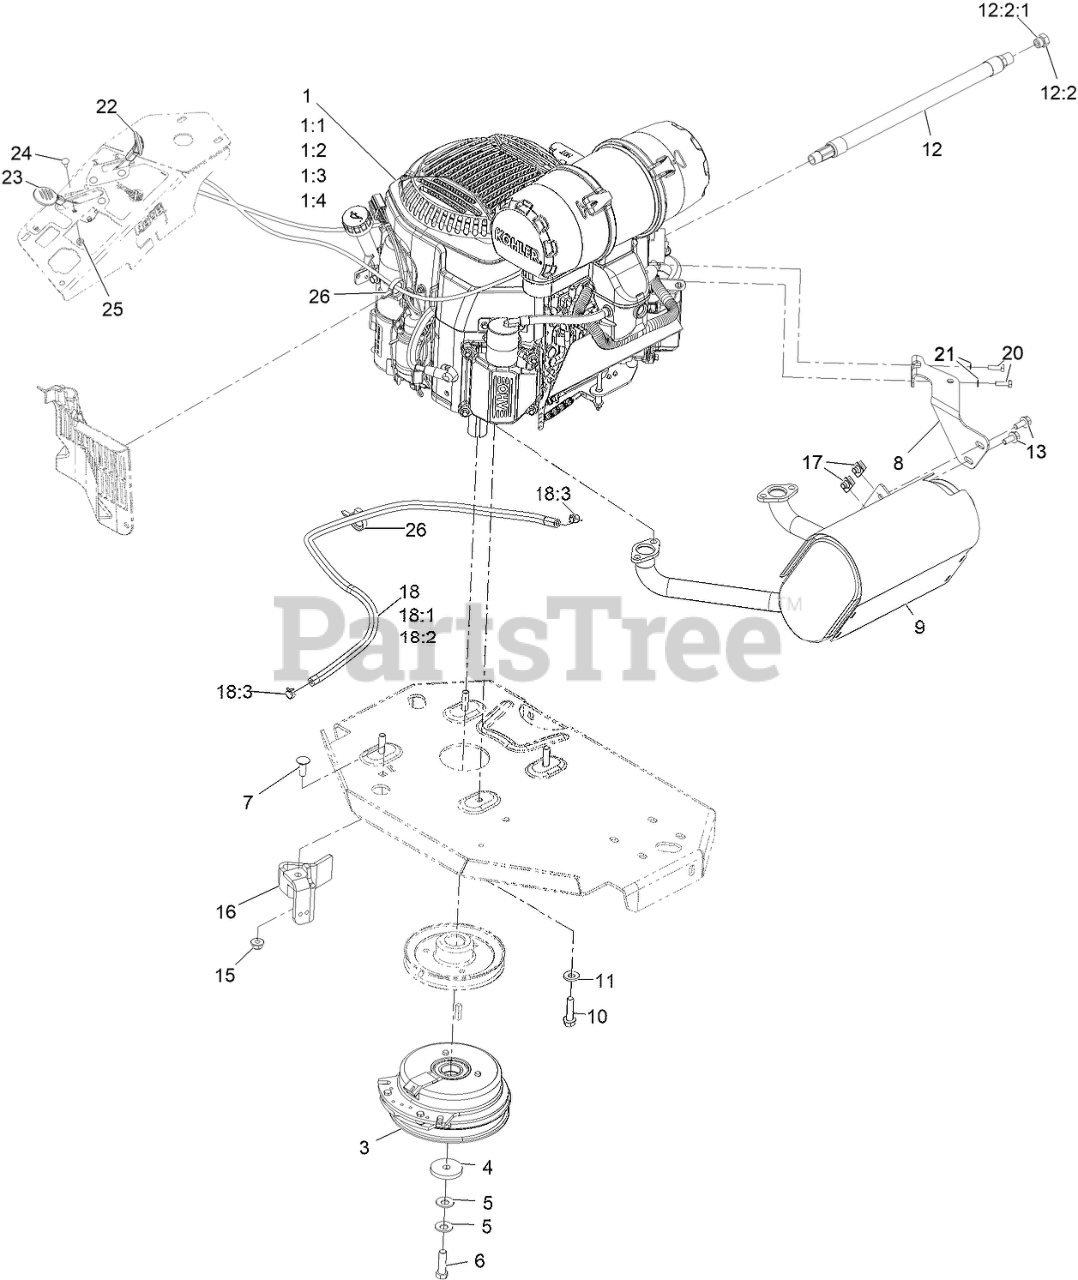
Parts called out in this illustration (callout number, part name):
1:1	Kohler 52 050 02-S Engine Oil Filter
1:2	Kohler 25 083 01-S Engine Air Filter
1:3	Kohler 25 083 04-S Safety Filter
1:4	Kohler 24 050 13-S Fuel Filter
3	CLUTCH KIT
4	WASHER-CLUTCH
5	WASHER-SPRING
6	SCREW-HH 7/16-20 X 1 1/2 W/LOCTITE
7	SCREW-CARR
8	MUFFLER BRACKET KIT
9	MUFFLER KIT
10	SCREW-HWH
11	WASHER-BELLEVILLE
12	OIL DRAIN HOSE ASM
12:2	PLUG-HH
12:2:1	O-RING
13	SCREW-HHF
15	NUT-HF, NI
16	CLUTCH-ANCHOR
18	FUEL LINE ASM
18:1	HOSE-FUEL
18:2	SLEEVE-THERMAL
18:3	CLAMP-HOSE
20	SCREW-HH M6-1 X 20Mm W/Patch
21	WASHER-SPRING
22	ASM, CHOKE CABLE
23	ASM,THROTTLE CABLE
24	BOLT-CARR
25	NUT-LOCK, NI
26	CLAMP-HOSE
